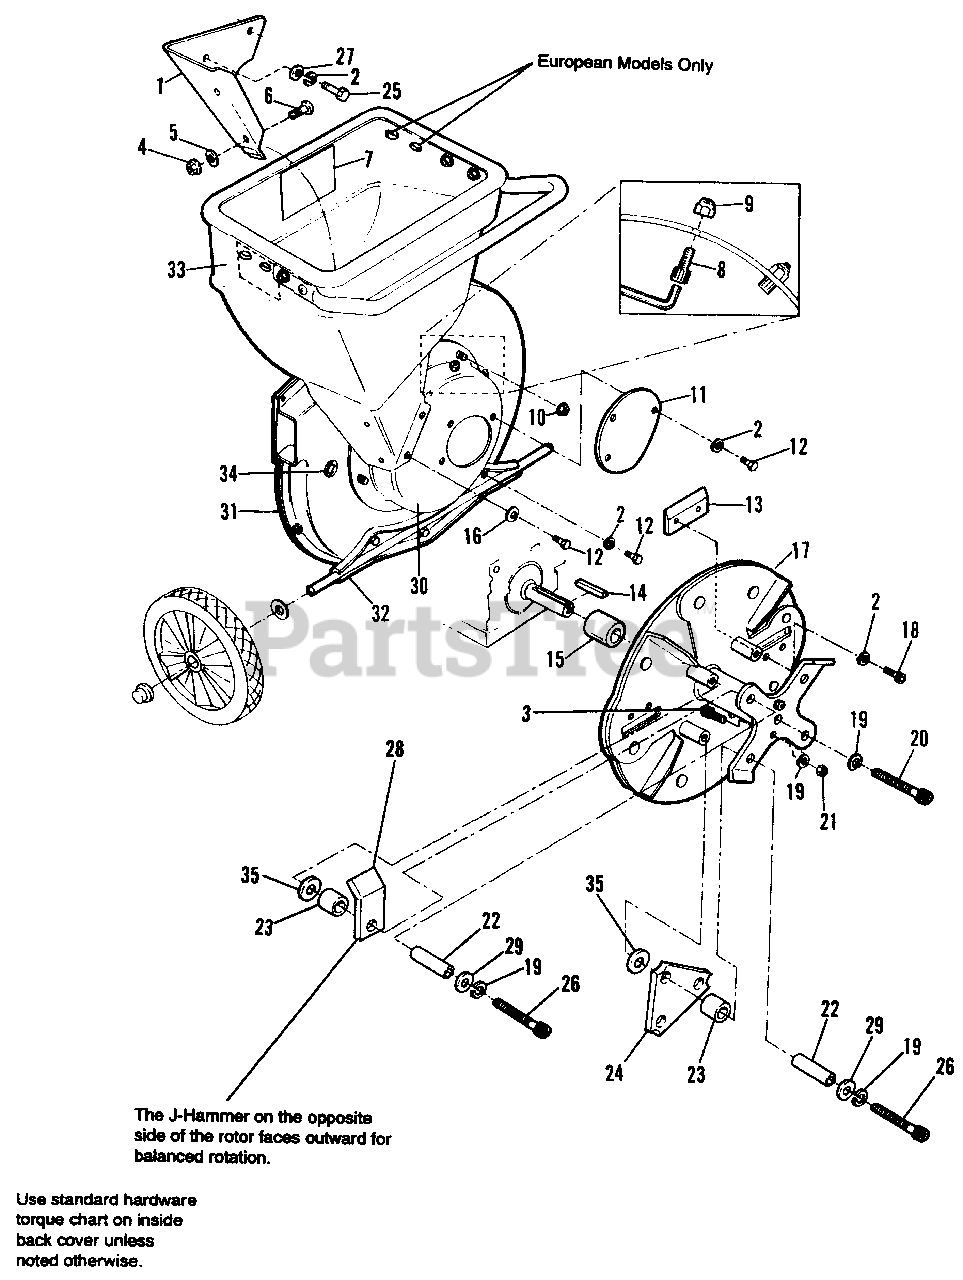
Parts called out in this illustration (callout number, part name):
1	HOPPER LINER
2	* Lockwasher, Split, 5/16
3	CAPSCREW, Socket Hd., 3/8-16 x 5/8
4	NUT, 2-way Lock, 1/4-20
5	WASHER, Flat, 1/4
6	CAPSCREW, Phillips Hd., 1/4-20 x 5/8
7	DECAL, Caution
8	CAPSCREW, Socket Hd., 5/16-18 x 1/2
9	NUT, Nylock, 5/16-18
10	NUT, Flange, Hex, 5/16-18
11	COVER, Rotor Housing
12	CAPSCREW, Hex Hd., 5/16-18 x 1/2
13	CHIPPER KNIFE
14	KEY, 1/4 Sq. x 1-7/8
15	SPACER, Rotor (5/14 Only)
15	SPACER, Rotor (8/14 Only)
16	WASHER, Flat, 5/16
17	* ROTOR, 1" Hub
18	CAPSCREW, Socket Hd., 5/16-24 x 5/8
19	* LOCKWASHER, Split, 3/8
20	CAPSCREW, Socket Hd., 3/8-24 x 2
21	NUT, Hex, 3/8-16
22	* SPACER, Tube
23	* SPACER, 3/4" O.D., 3/4" Long (5/14 Only)
23	* SPACER, 1"0.D., 33/64"Long (8/14 0nly)
24	HAMMER, Triangular
25	CAPSCREW, Hex Hd., 5/16-18 x 3/4
26	* CAPSCREW, Hex, Socket Hd., w/Patch, 3/8 16 x 2, Gr. 8
27	WASHER, Flat, 5/16
29	* WASHER, Flat, 7/8 O.D.
30	HOUSING, Rotor
31	HOUSING, Fan
32	AXLE ASSEMBLY
33	DECAL Danger
34	Plug BUTTON
35	WASHER, Plain, 1/2 x 1-1/4 x 3/16 (8/14 0nly)
